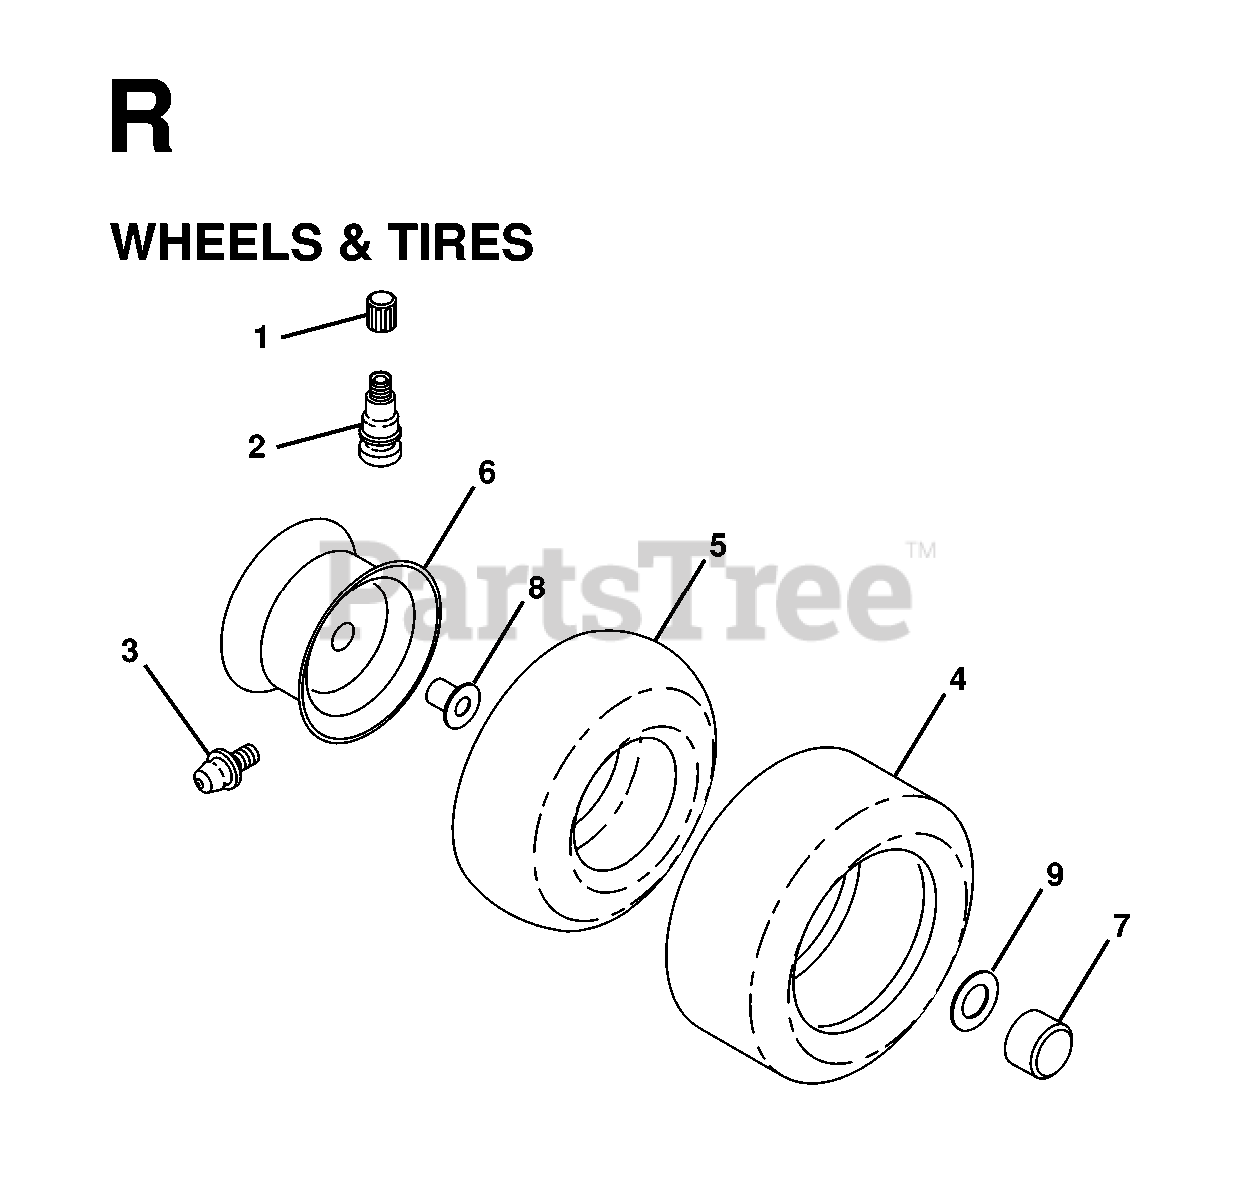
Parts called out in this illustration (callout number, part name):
2	VALVE STEM LT
3	FITTING LT
4	TIRE FRONT 15X6-6
5	TUBE.5.3/4.5/6
5	TUBE.16X6.5/7.5-8
6	RIM REAR 8"
6	RIM
7	CAP.HUB.FRONT.LT.BLACK
8	BEARING T
